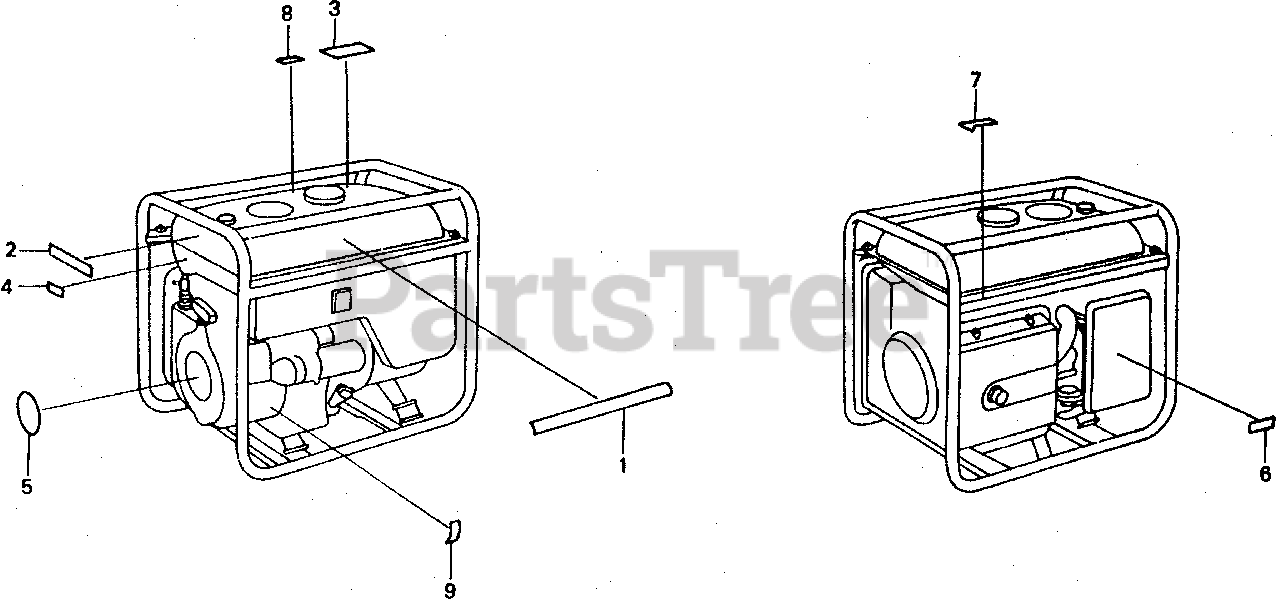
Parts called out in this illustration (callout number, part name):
1	EMBLEM (NOT AVAILABLE)
2	PLATE, CAUTION (NOT AVAILABLE)
3	MARK, CAUTION (ENGLISH/FRENCH)(SPANISH)
4	MARK, CHOKE
5	LABEL, OIL ALERT
6	MARK, AIR CLEANER (ENGLISH)
7	MARK, EX. CAUTION (ENGLISH/FRENCH)
8	MARK, CAUTION (CO)(ENGLISH/FRENCH)(SPANISH)
9	MARK, OIL CAUTION
